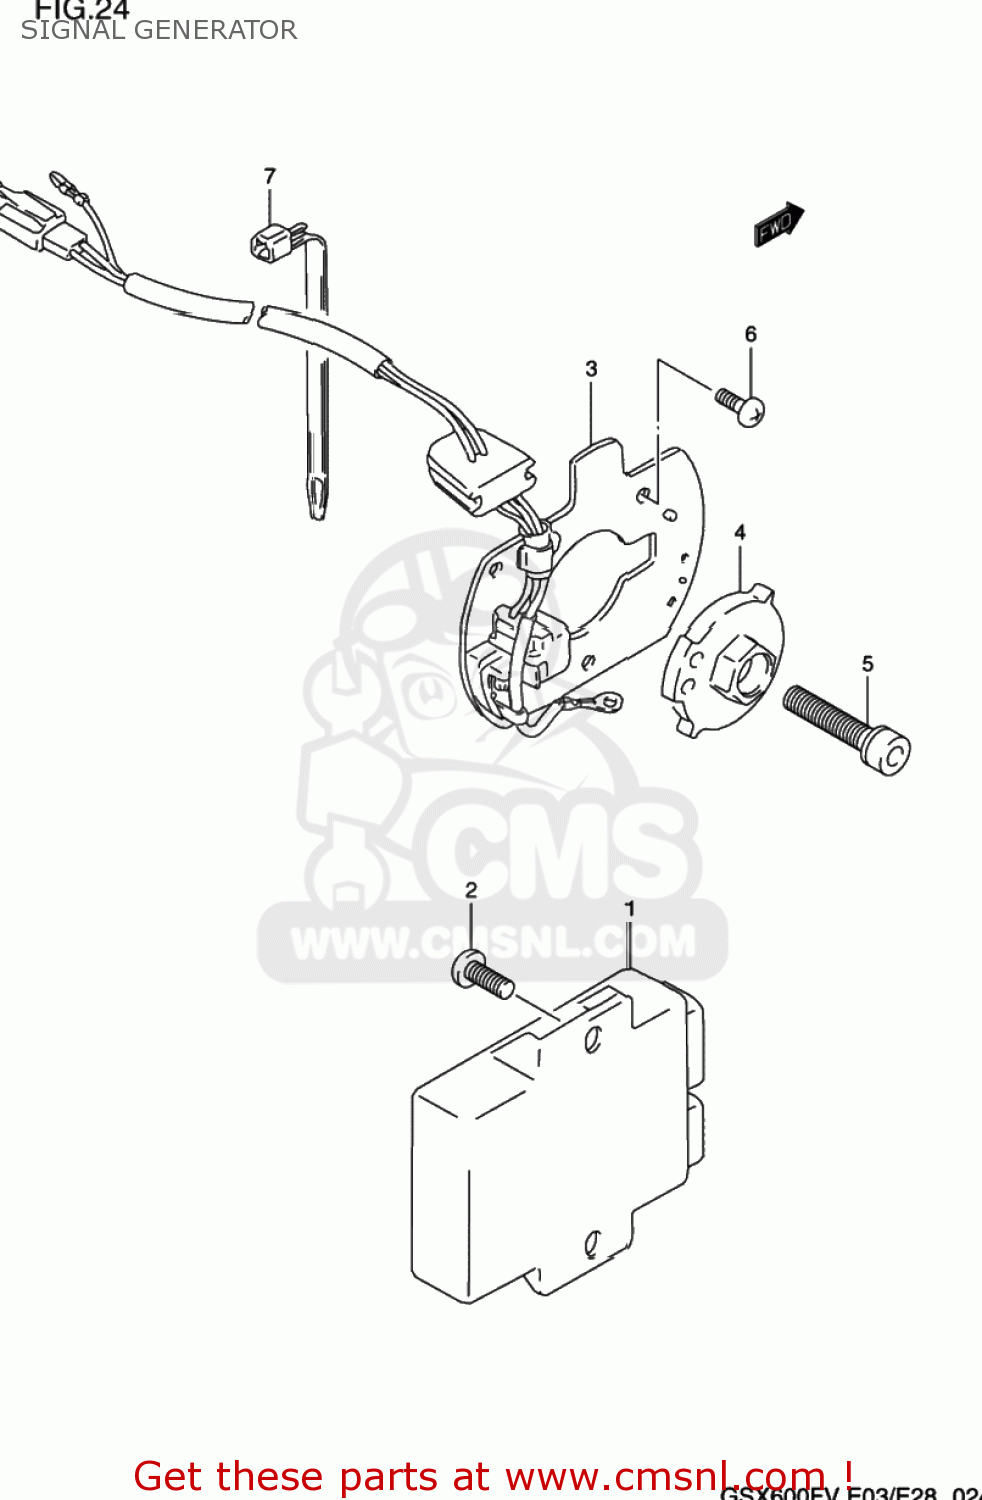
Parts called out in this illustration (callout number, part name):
1	IGNITOR ASSY
2	SCREW 6X12
3	GENERATOR ASSY,SIGNAL
4	ROTOR,SIGNAL GENERATOR
5	BOLT
6	SCREW
7	CLAMP(L:95)
